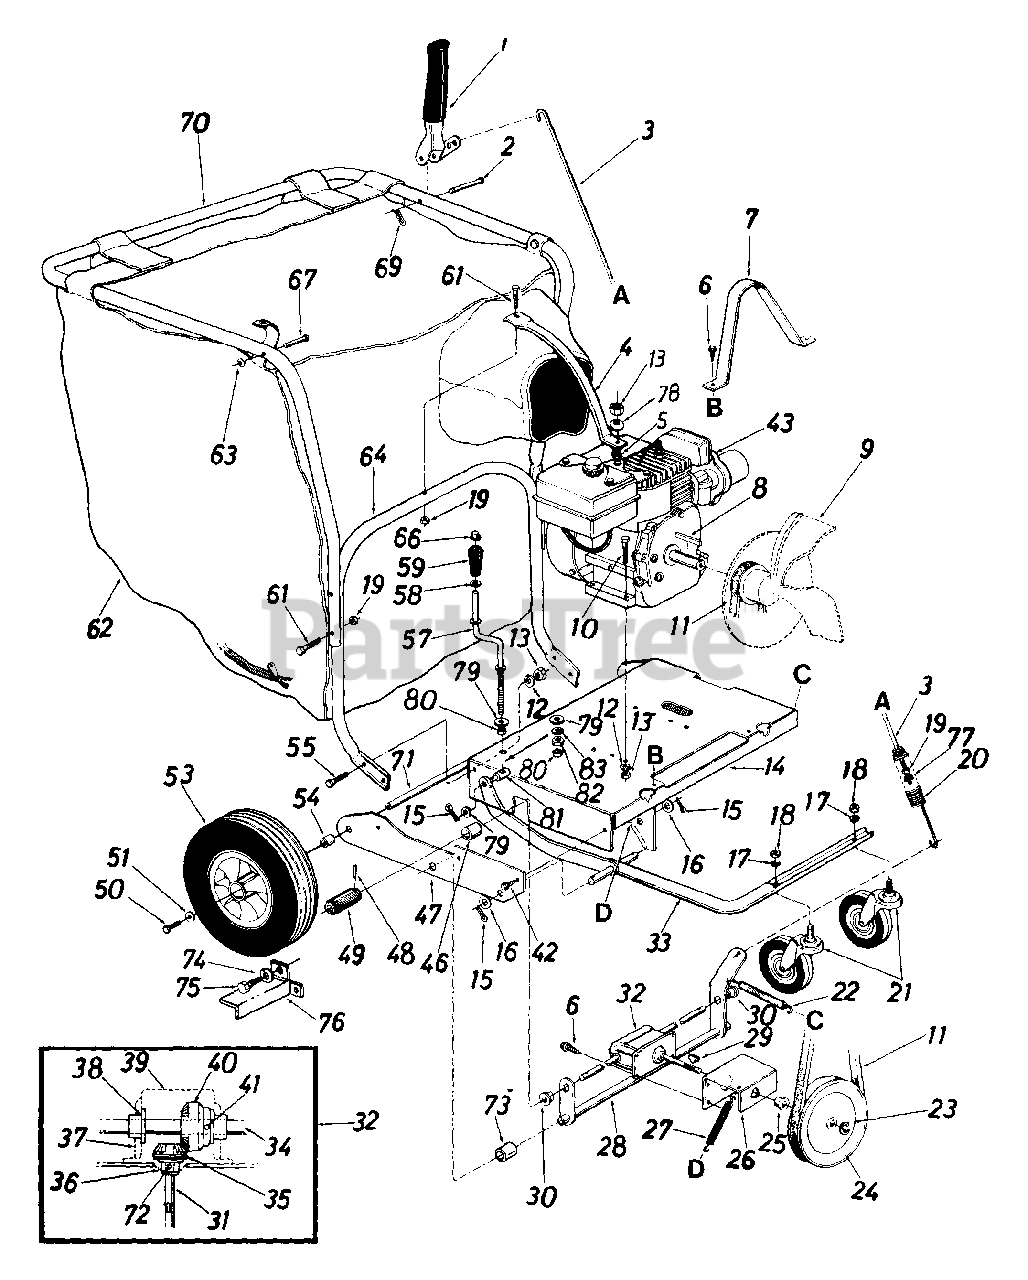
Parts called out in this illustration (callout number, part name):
3	Clutch Rod 32" Lg.
4	Handle Brace (Painted)
5	Part of Engine
6	Hex Wash. Hd. AB-Tap Scr. 1/4" x .62" Lg.
11	"V"-Belts
12	L-Wash. 5/16" I.D.
13	Hex Nut 5/16-18 Thd.
16	Fl-Wash..63" I.D. x 1.25" O.D.
17	L-Wash. 1/2" I.D.
18	Hex Nut 1/2-13 Thd.
19	Wex Cent. L-Nut 1/4-20 Thd.
20	Extension Spring .78" O.D. x .75" Lg.
21	Swivel Caster Wheel 5" Dia. x 1.25"
22	Extension Spring .38" O.D. x 7.50" Lg.
23	Snap "E"-Ring .50" Dia. Shaft
24	"V"-Pulley 5/8" x 6.50" O.D.
25	Flange Bearing .502" I.D.
28	Clutch Bracket Ass'y.
29	02 Woodruff Key 3/32" Dia. x .81" Lg.
30	Hex Flange Bearing Bronze .625" I.D.
31	Pinion Shaft .50" Dia. x 5"
32	Gear Box Ass'y. Comp.
35	Bevel Gear .50" I.D. x 14 Teeth
36	Flange Bearing .503" I.D.
37	Gear Box
38	Flange Bearing .630" I.D.
39	Gear Box Cover
40	Bevel Gear .62" I.D. x 28 Teeth
41	Spring Pin Spiral 3/16" Dia. x 1.25" Lg.
42	Hex Wash. Hd. AB-Tap Scr. 5/16" x .75" Lg.
43	Engine
46	Spacer .63" I.D. x .88" O.D. x .56" Lg.
49	Drive Pinion
50	Hex Locking Bolt 5/16-24 x .62" Lg.
51	Fl-Wash. .34" I.D. x .87" O.D.
53	Wheel Ass'y. Comp. 12" x 3"
54	Spacer .63" I.D. x 1.0" O.D. x .94" Lg.
55	Hex Bolt 5/16-18 x .75" Lg.
57	Height Adjustment Crank
58	Fl-Wash .385" I D. x.62" O.D.
59	Crank Knob
61	Hex Bolt 1/4-20 x 1.75" Lg
62	Vacuum Bag - Felt
63	Push Speed Nut .25" Dia. Stud
66	Push Nut 3/8" Dia
67	Stud Pin .250" Dia. x 1.75"
69	Internal Cotter Pin 3/8" Dia.
70	Upper Handle (Painted)
71	Rear Axle
72	Spring Roll Pin 5/32" Dia. x 1.12
73	Spacer .82" I.D. x 1.0" O.D x .305 Lg.
74	L-Wash..265" I.D.
75	Hex Self-Tap Scr. 1/4" x 3/8" Lg.
78	Belleville Washer
79	Fl-Wash..35" I.D x.87" O.D.
80	Spacer .38" .D. x .50" O.D. x .18" Lg.
81	Ferrule 3/8-8 x .38" Dia.
82	Hex Nut 3/8-8 Thd.
83	L-Wash. 3/8" I.D.
14530-0498	PLATE-SIDE-RH - OLD CUB YELLOW (0498)
14530-0499	PLATE-SIDE-RH - CUB BEIGE (0499)
14530-0637	PLATE-SIDE-RH - POWDER BLACK (0637)
14530-0638	PLATE-SIDE-RH - MTD/TROY-BILT RED (0638)
16273-0498	Double Caster Arm Assembly, Black - OLD CUB YELLOW (0498)
16273-0637	Double Caster Arm Assembly, Black - POWDER BLACK (0637)
16273-0638	Double Caster Arm Assembly, Black - MTD/TROY-BILT RED (0638)
16273-0648	Double Caster Arm Assembly, Black - TECH GRAY (0648)
16273-0662	Double Caster Arm Assembly, Black - OYSTER GRAY (0662)
16273-0674	Double Caster Arm Assembly, Black - YARDMAN YELLOW (0674)
16273-0691	Double Caster Arm Assembly, Black - BLACK JACK (0691)
16273-0709	Double Caster Arm Assembly, Black - MASTERCRAFT GREEN (0709)
